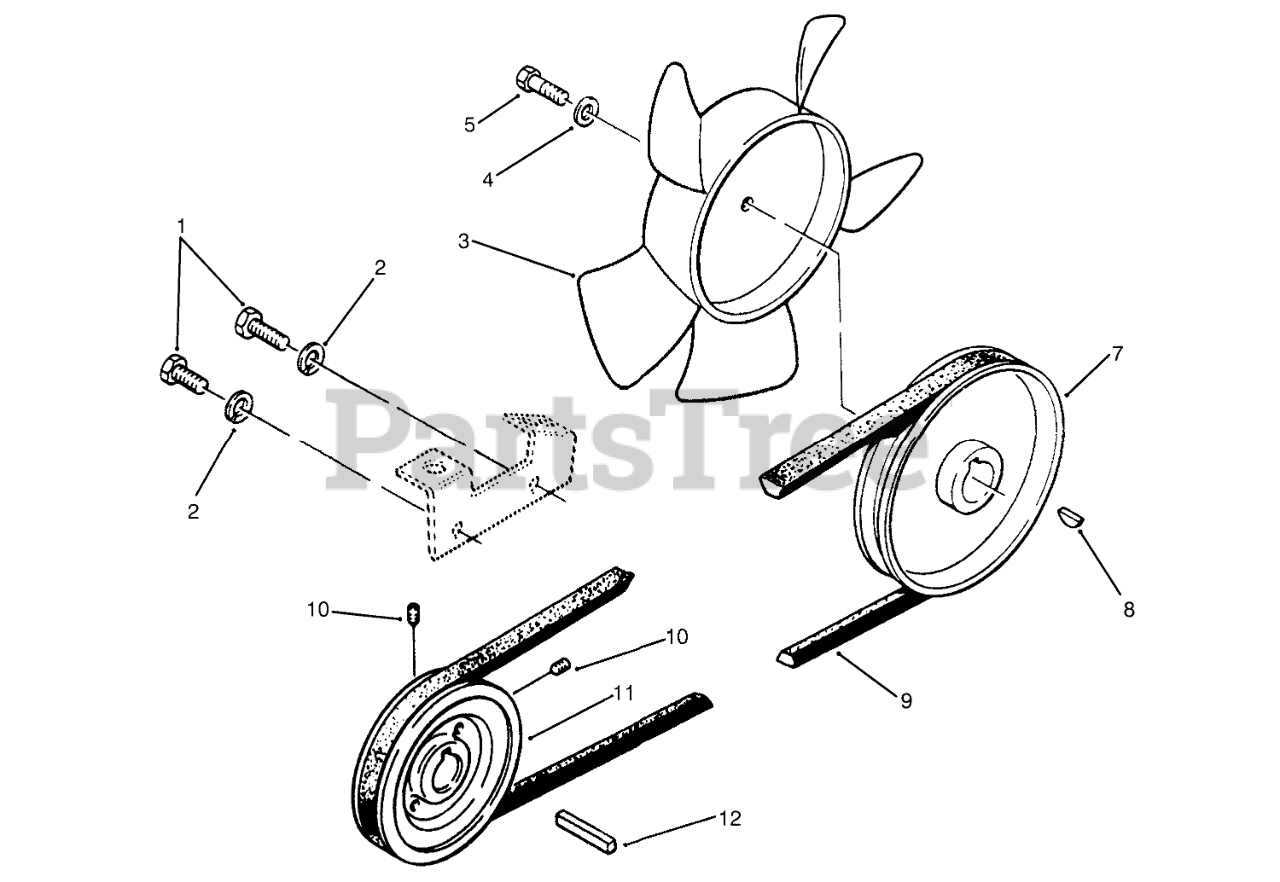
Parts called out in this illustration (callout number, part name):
1	SCREW-HH
2	WASHER-LOCK
3	NYLON FAN-L-CW
4	WASHER
5	SCREW-HEX HD CAP
7	PULLEY
8	KEY-WOODRUFF
9	BELT-V
10	SCREW-SET, HSH
11	PULLEY
